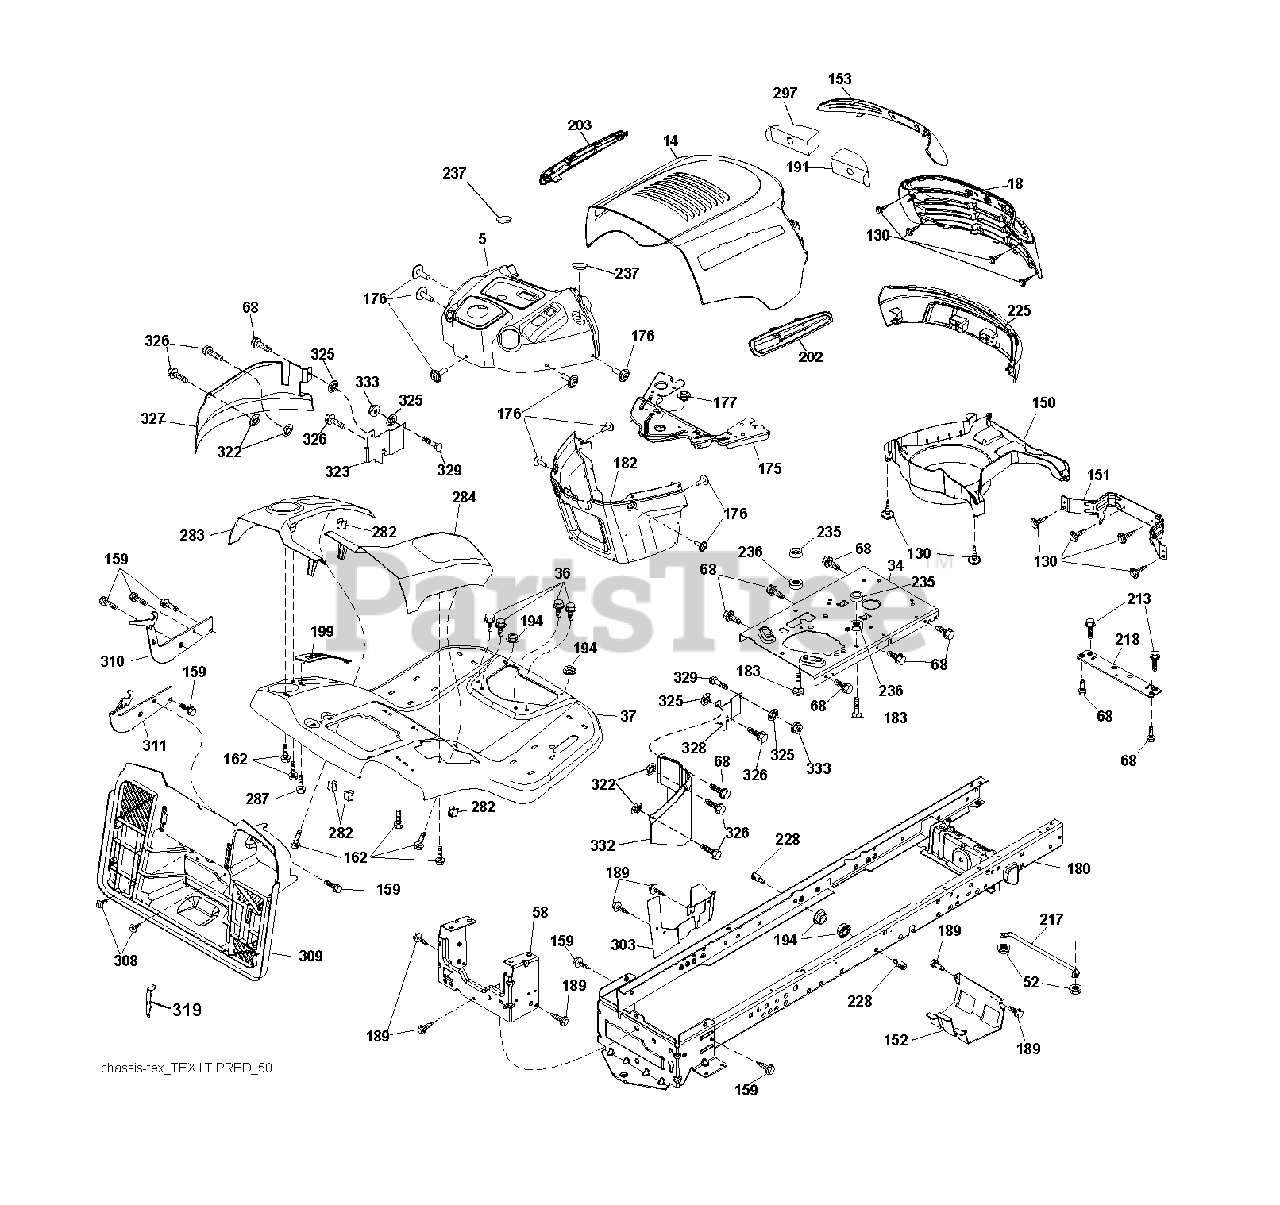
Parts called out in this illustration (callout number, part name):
34	PLATE.ENGINE.WELDED.CHASSIS
36	SCREW 5/16"
52	LOCKNUT
58	DRAWBAR UPPER 2PC SMALL FENDER
130	SCREW.#10 X 0.750.BOS THREAD
151	BRACKET.PIVOT.ALPHA.LT
152	SHIELD BROWNING
159	SCREW, 3/8-16X3/4
162	SCREW.HI-LO.CONSOLE
175	CROSSMEMBER
176	SCREW.#10-24X5/8.RN.QU
177	BUSHING STEERING
182	DASH.LWER.PREDATOR/HUSQ.LT
183	BOLT.5/16-18X1-1/4 FULL THD
189	SCREW
191	INSERT.REFLECT.PREDATOR.LT.RH
194	NUT LOCK HEX FLANGE 5/16-18
213	BOLT
217	ROD.PIVOT.HOOD
218	X-PIECE.HOOD.STOP.NON/
228	STUD.FASTNER.W/ANTI-ROTATE
235	SPACER FENDER
236	NUT.CENTERLOCK.5/16-
237	PLUG.MOUNT.CARGO.BLK
282	CLIP.RETAINER.CONSOLE.LT.HUSQ
297	REFLECTOR.INSERT.PRED.LH.LT
308	BOLT, 5/16-18 X 1 3/4
322	PALNUT 1/4
326	SCREW 14-20 X 5/8
329	BOLT
333	NUT.71038.31-18.HEX.NYLOCK
